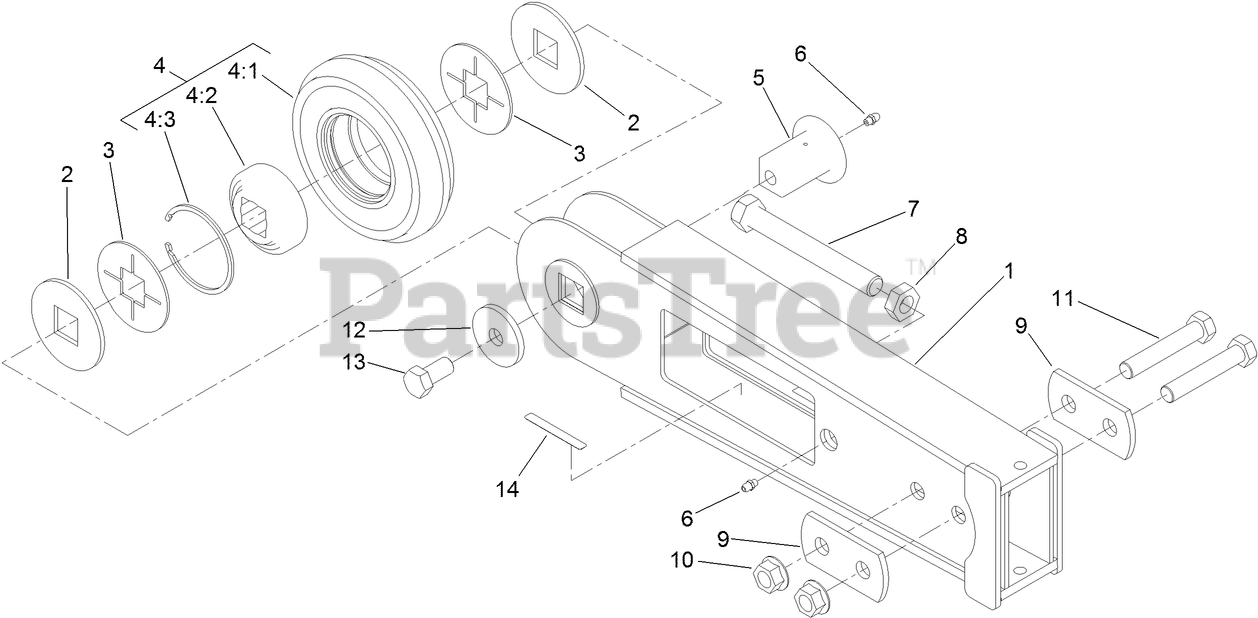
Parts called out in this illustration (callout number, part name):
1	BOOM ASM
2	CAP-ROLLER
3	SPACER-ROLLER
4	TRENCHER ROLLER ASM
4:1	ROLLER-NOSE
4:2	BEARING
4:3	RING-RETAINING
5	AXLE-ROLLER
6	FITTING-GREASE
7	BOLT-ADJUSTMENT
8	NUT-JAM
9	PLATE-SUPPORT
10	NUT-FLANGE
11	SCREW-HH
12	WASHER
13	SCREW-HH
14	DECAL-WARNING
